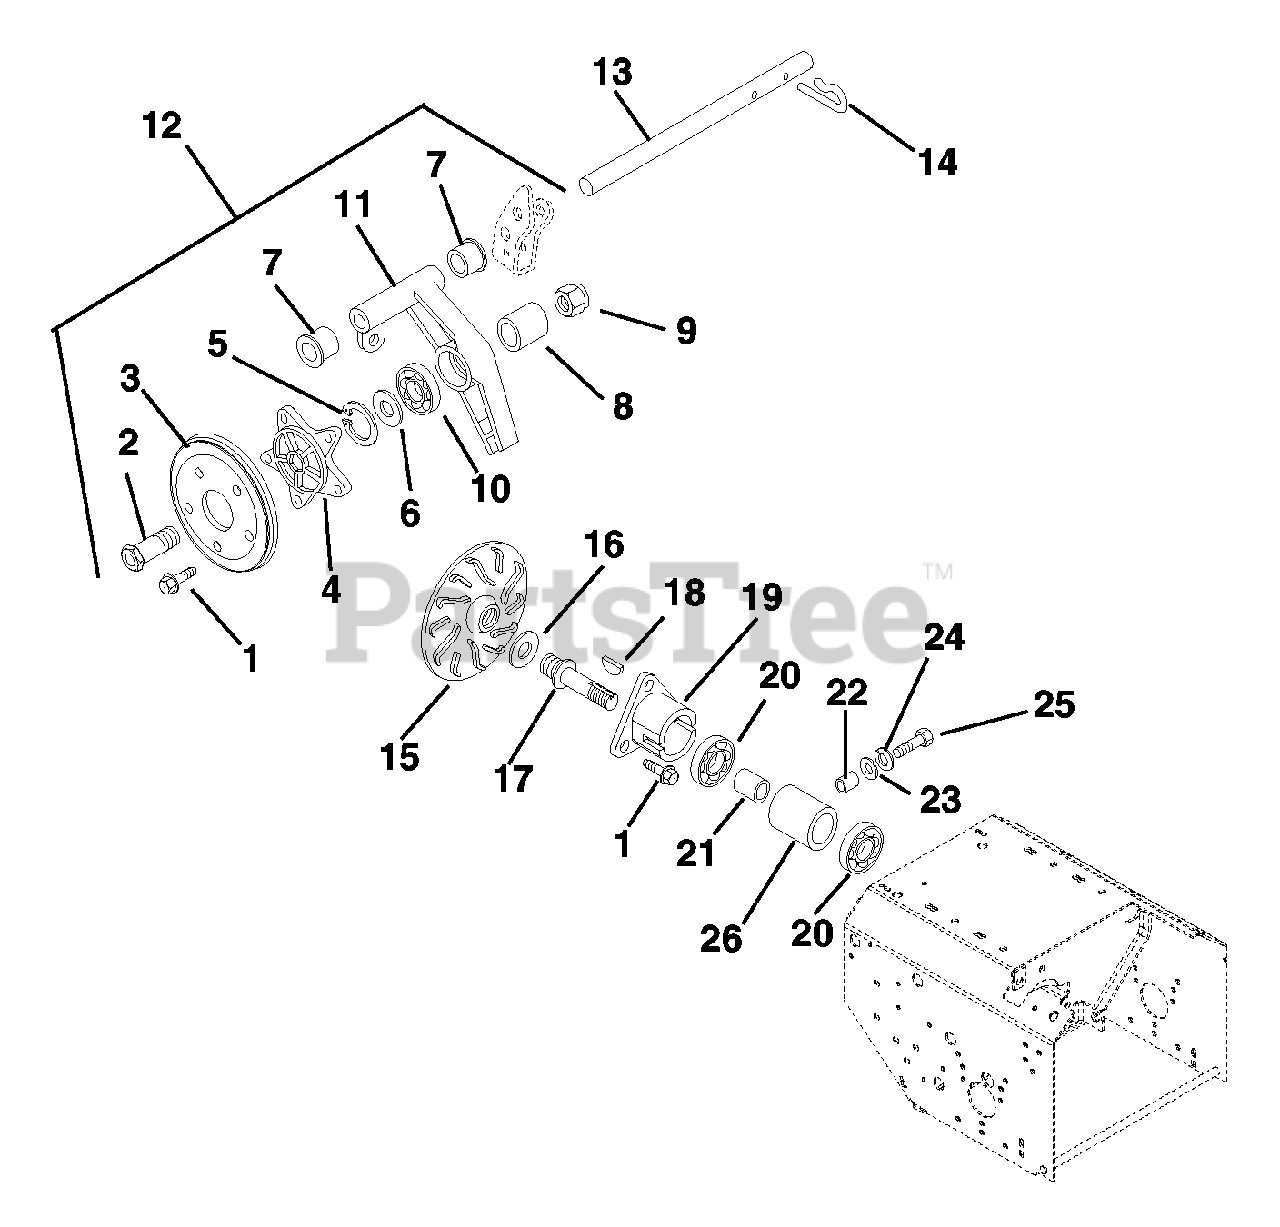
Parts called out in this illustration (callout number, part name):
1	Screw, Tapping .31-18 x .50
2	Spindle Hub
3	Friction Disc
4	Disc Hub
5	Ring, Retaining Internal 1.75 x .062
6	Washer, Flat Steel .88 x 1.25 x .062
7	Bushing, Flange .63 x .750 x .50 x .88
8	Bushing, Sleeve .88 x 1.25 x .53
9	Nut, Locking Nylon .88-14
10	Bearing, Ball .88 x 1.75 x .50
11	Carrier
12	Friction Wheel Assembly
13	Carrier Shaft
14	Pin, Spring Clip
15	Drive Plate
16	Drive Disc Spacer 1.30 x .76 x .19
18	Key, Feather .125 x .50 x .194
19	Housing Mount
20	Bearing .63 x 1.38 x .43
21	Bearing Spacer
23	Washer, Flat Steel .34 x .69 x .065
24	Washer, Lock .31 x .078
25	Bolt, Hex .31-18 x 1.00 Grade 5
26	Spindle Housing
